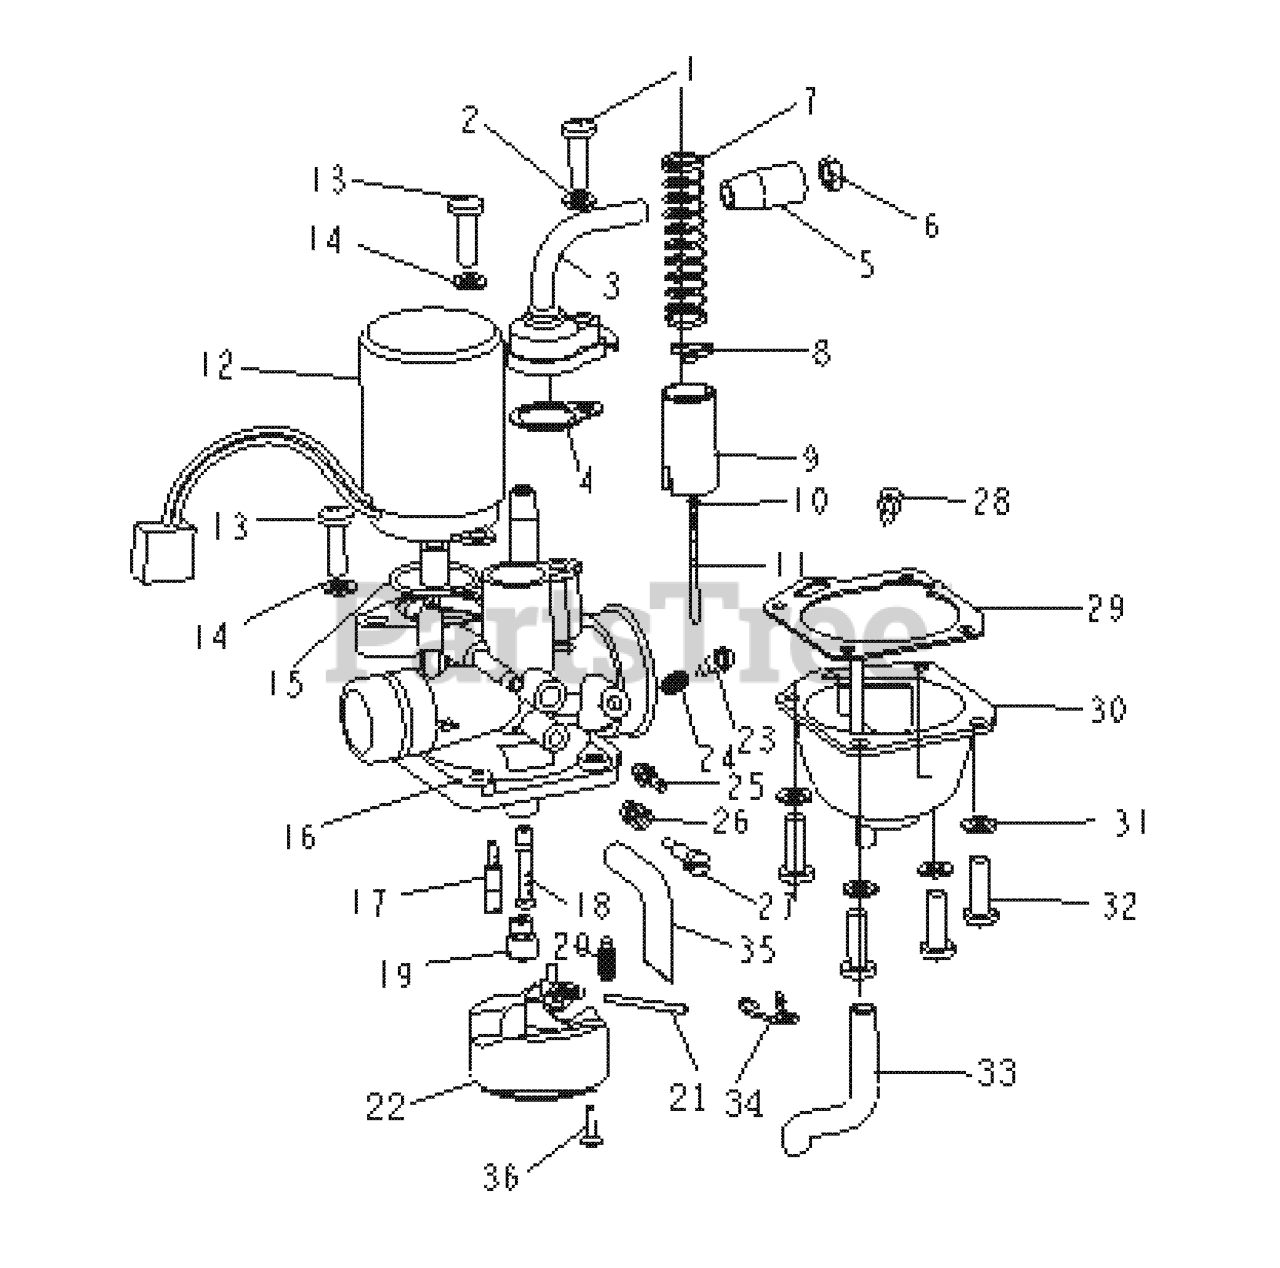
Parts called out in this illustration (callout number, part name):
5	BENT PIPE, TCC
6	SCREW NUT, TCC BENT PIPE
7	SPRING, RETURN
8	CLIP, V SHAPE
9	VALVE, PISTON
11	NEEDLE, JET
12	THERMO ASSY
15	O -RING, THERMO ASSY
16	BODY, CARBURETOR
17	JET, IDLE
18	JET, NEEDLE
20	VALVE, NEEDLE
21	PIN, FLOAT
23	SCREW, AIR
24	SPRING, AIR SCREW
25	PIPE, OIL
26	SPRING, ADJUSTING
27	SCREW, IDLE SPEED
28	SCREW, DRAIN
29	GASKET, FLOAT CHAMBER
30	CHAMBER, FLOAT
33	HOSE, DRAIN
37	CARBURETOR ASSY
